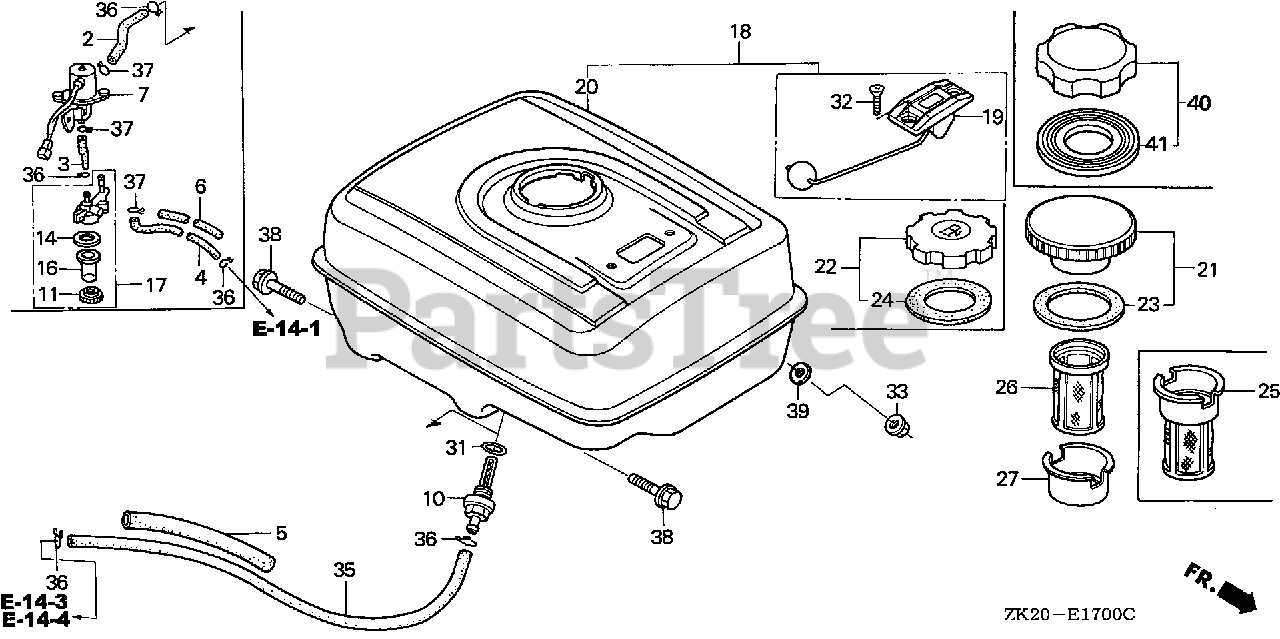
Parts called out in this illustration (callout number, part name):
5	RUBBER, SUPPORTER (107MM)
10	JOINT, FUEL TANK
20	TANK, FUEL *NH31* (MCKINLEY WHITE)
31	O-RING (14MM) (ARAI)
31	O-RING (14MM) (NOK)
33	NUT, FLANGE (8MM)
35	BULK HOSE, FUEL (4.5X3000) (4.5X222)
36	CLIP, TUBE (B8)
38	BOLT, FLANGE (8X25)
40	CAP, FUEL FILLER (CHROME PLATED)
41	GASKET, FUEL FILLER CAP (39X62X3) (TOUYOUSYA)
